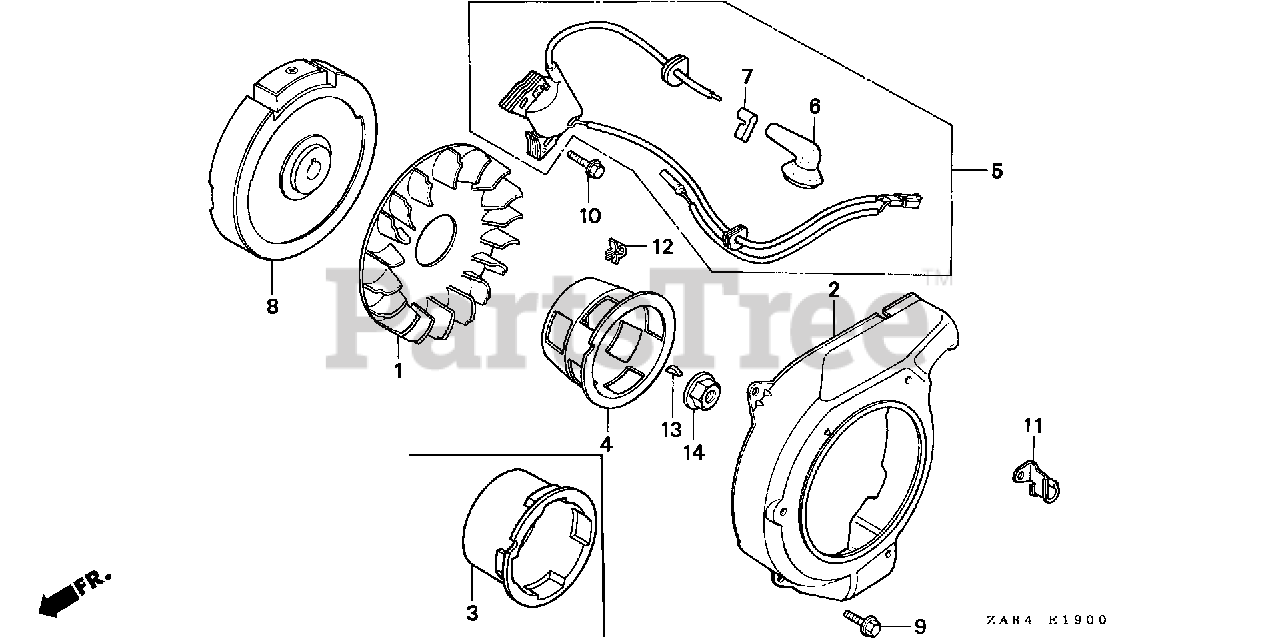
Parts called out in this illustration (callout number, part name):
1	FAN, COOLING
2	COVER, FAN
3	PULLEY, STARTER
4	PULLEY, STARTER
5	COIL ASSY., IGNITION
6	CAP, IGNITION
7	TERMINAL, PLUG
9	BOLT, FLANGE (6X12) (CT200)
10	BOLT, FLANGE (6X25)
11	CLIP, FUEL TUBE
12	CLIP, CABLE (A)
13	KEY, WOODRUFF (3MM)
14	NUT, FLANGE (12MM)
